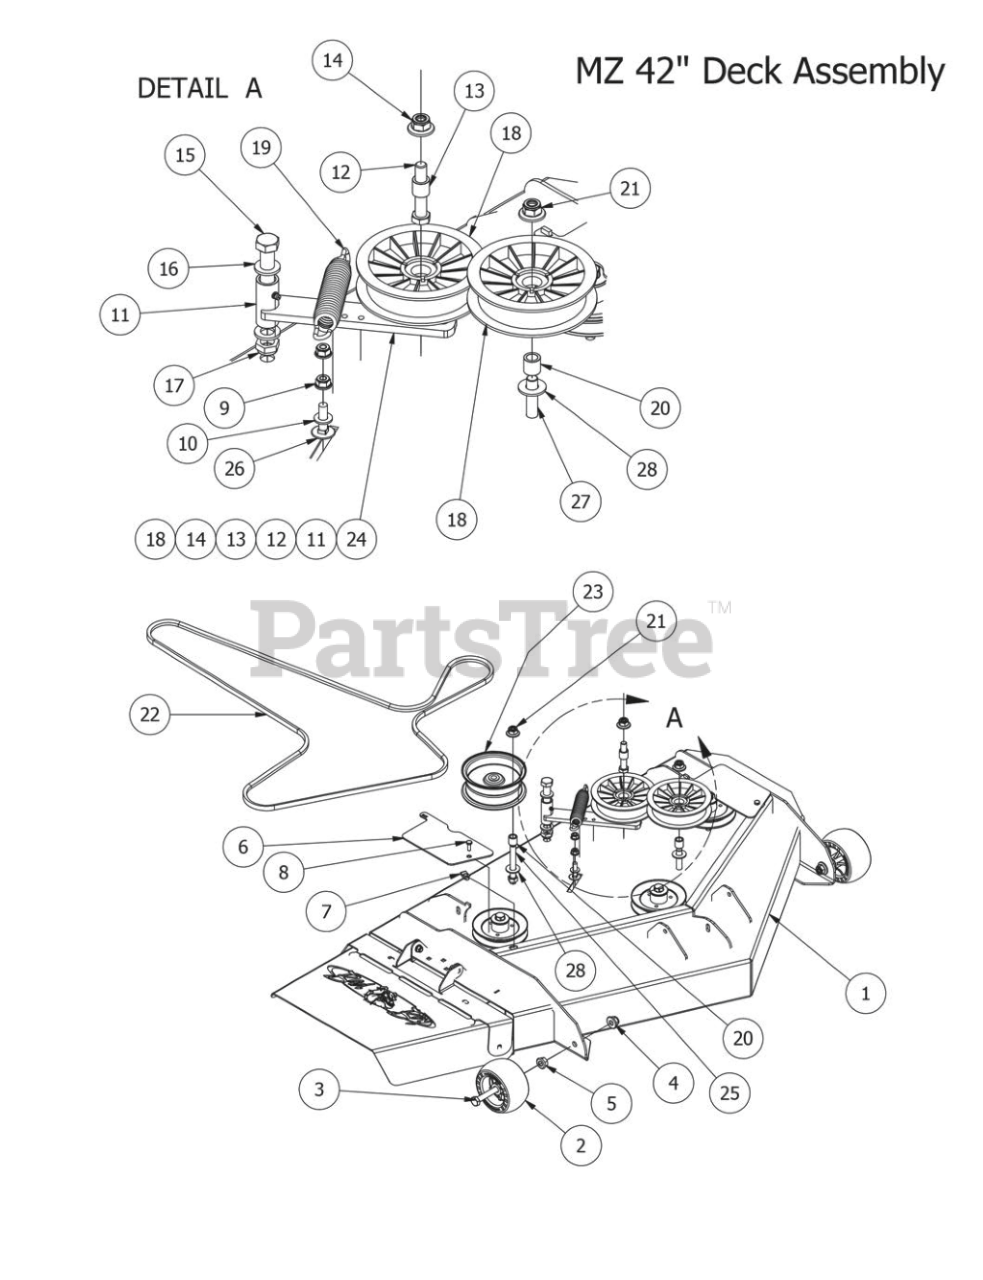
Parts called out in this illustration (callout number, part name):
1	Mz 42 Deck
2	Deck Wheel
3	1/2 x 3 1/2 Flange Bolt Grade 8
4	1/2-13 Nylon Flange Nut-Orange
5	1/2-13 Hex Flange (GR.G) ZC
6	MZ42 Pulley Cover
7	1/4-20 Cage Nut
8	1/4" x 3/4" Hex Bolt
9	3/8" Nylock Flange Nut
10	3/8" Flat Washer
11	Deck Idler
12	1/2" x 2 3/4" Hex Bolt
13	3/4 OD x 1/2 ID x 3\4 Length
14	1/2-13 Nylon Flange Nut-Orange
15	5/8" x 4" Hex Bolt
16	.635 ID Plastic Washer
17	5/8" Nylock (1/2 Jam)
18	Plastic Idler Pulley
19	Deck Idler Spring MZ
20	3/4 OD x 1/2 ID x 3\4 Length
21	1/2-13 Nylon Flange Nut-Orange
22	42" Deck Belt- B120
23	5 3/4" Deck Idler Pulley
24	Parts 11,12,13,14,18 make up the deck idler assembly
25	1/2-13 x 3 1/2 GR 5 Hex Bolt
26	3/8 x 1-1/2 Carriage Bolt
27	1/2-13 x GR 5 Hex Bolt Zinc
28	1/2" Washer (Grade 8)
